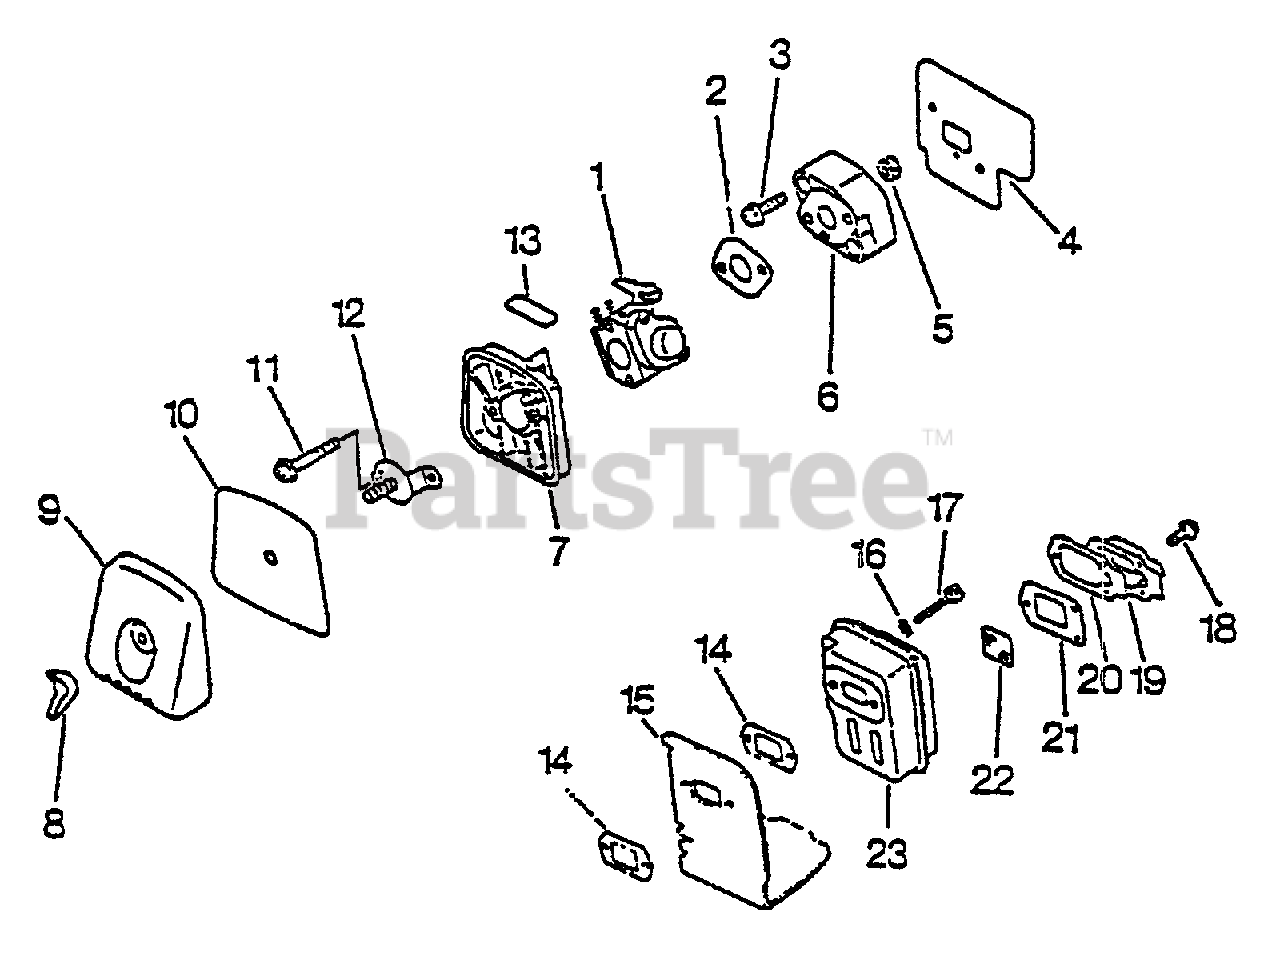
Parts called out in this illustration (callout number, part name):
1	CARBURETOR - C1U-K26
2	GASKET, INTAKE
3	SCREW 5×22
4	GASKET, INTAKE
5	NUT M5
6	INSULATOR, INTAKE
7	CASE, AIR FILTER
8	WINGNUT - 6
9	COVER, AIR FILTER
10	FILTER, AIR
11	SCREW 5×64
12	PLATE, PREVENT
13	LABEL - CHOKE
14	GASKET, EXHAUST
15	COVER, MUFFLER
16	WASHER, FLAT 5.5×10×0.8
17	BOLT 5×55
18	SCREW 4×10
19	GUIDE, EXHAUST - INNER
20	GUIDE, EXHAUST
21	GASKET, EXHAUST
22	SCREEN, SPARK ARRESTER
